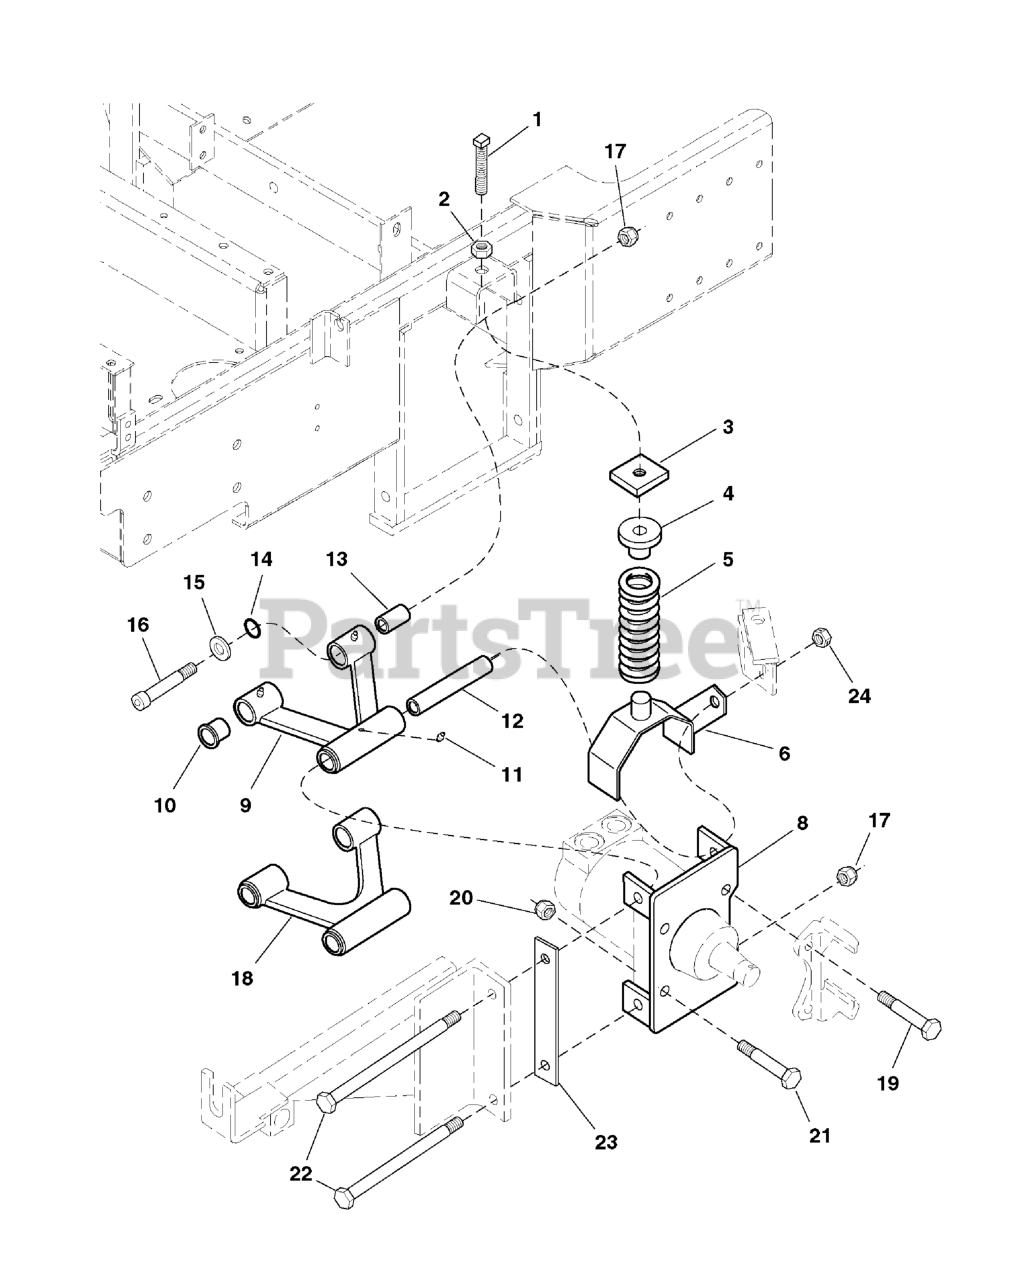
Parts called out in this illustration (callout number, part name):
1	SET SCREW, Square Head, 1/2-13 x 3
2	NUT, 1/2-13 Hex Jam
3	SPRING COMPRESSION PLATE
4	SPRING RETAINER
5	SPRING, SUSPENSION
6	SPRING SADDLE-LH
8	WHEEL MOTOR MOUNT
9	ASSM, UPPER A-ARM - RED
10	BUSHING, Flange
11	GREASE FITTING
12	PIVOT SLEEVE, Long
13	PIVOT SLEEVE, Short
14	O-RING
15	WASHER, A-Arm
16	BOLT, Allen Head, 1/2-13 x 3
17	NUT, 1/2-13 HEX NYLON LOCK
18	SUSPENSION A-ARM, Lower
19	BOLT, 1/2-20 x 3
20	NUT, Hex, Nylon Lock, 1/2-20
21	BOLT, 1/2-20 X 2-1/2" GD5 CZ
22	BOLT, 1/2-13 x 6-1/2
23	SPACER PLATE
24	NUT, 1/2-13 Hex Side Lock
